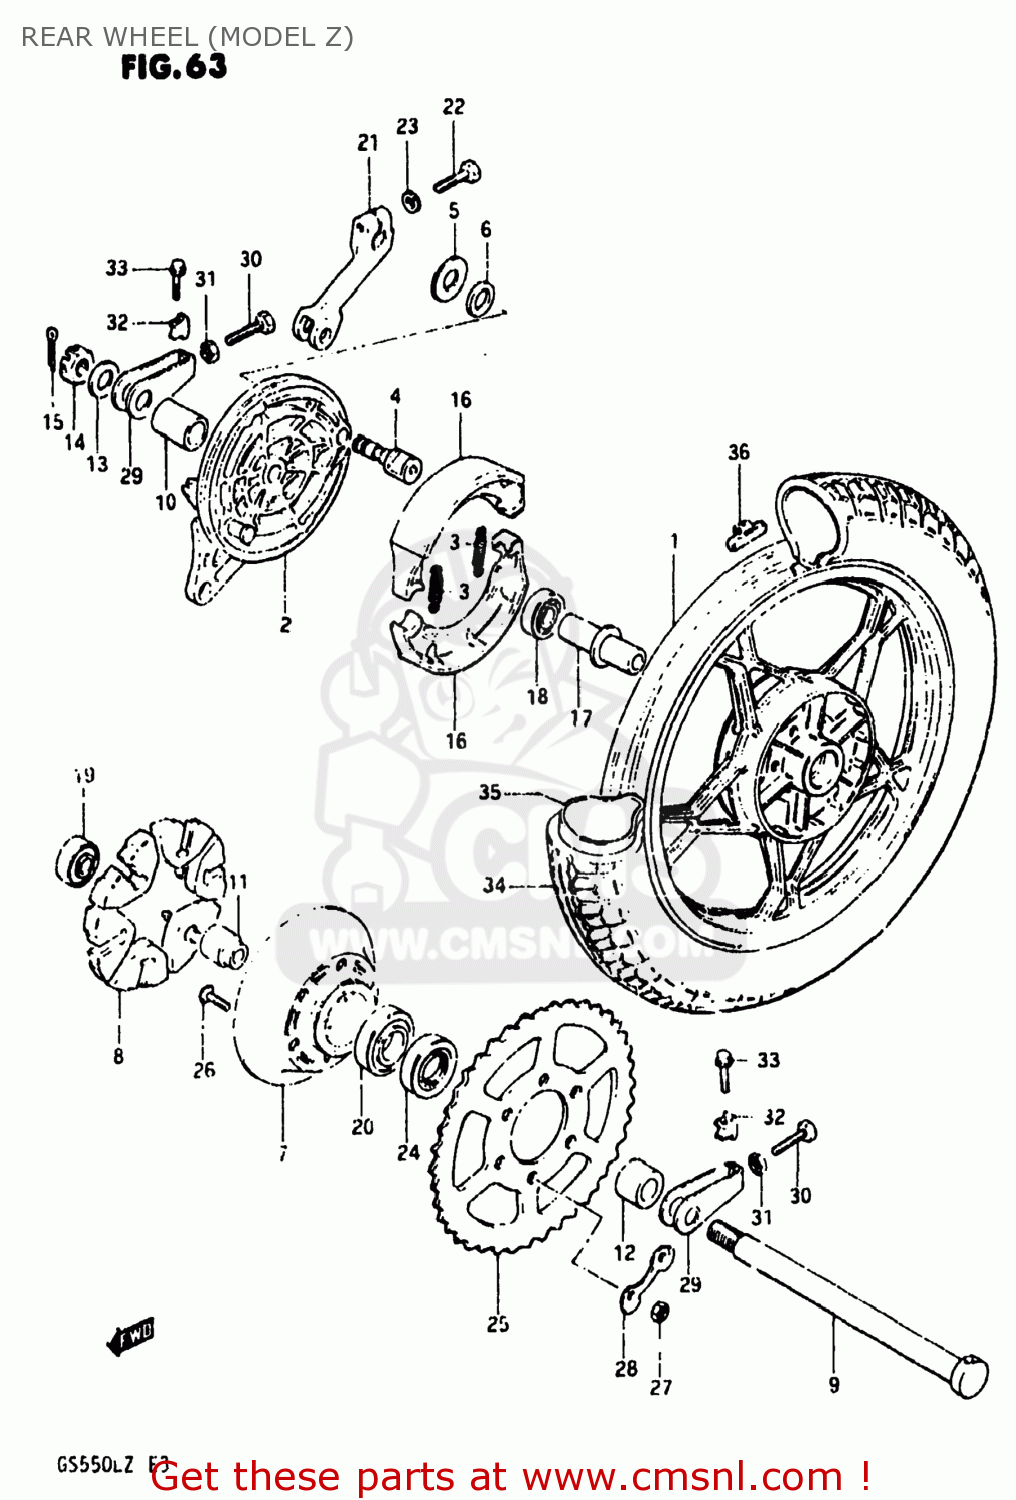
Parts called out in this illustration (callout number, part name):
1	WHEEL,REAR
2	PANEL,REAR HUB
3	SPRING,BRAKE SHOE
4	CAM,FRONT BRAKE
5	WASHER (15X24X1.6)
6	O-RING,BOSS
7	DRUM,REAR SPROCKET MOUNT
8	ABSORBER,RR HUB SHOCK
9	AXLE,REAR
10	SPACER
11	SPACER,REAR HUB BEARING
12	SPACER(17X30.5X22.3)
13	WASHER (17X30X3.2)
14	NUT
15	PIN,COTTER
16	SHOE,BRAKE
17	SPACER,REAR HUB BEARING
18	BEARING
19	BEARING
20	BEARING
21	LEVER,RR BRAKE CAM
22	BOLT
23	LOCK WASHER
24	SEAL,OIL(30.5X52X8)
25	SPROCKET,REAR (NT:49)
26	BOLT
27	NUT
28	WASHER
29	ADJUSTER,CHAIN
30	BOLT 8X50
31	NUT
32	SUPPORTER,CHAIN ADJUST
33	BOLT
34	TIRE
35	TUBE ASSEMBLY,WHEEL,INNER
36	BALANCER,WHEEL
